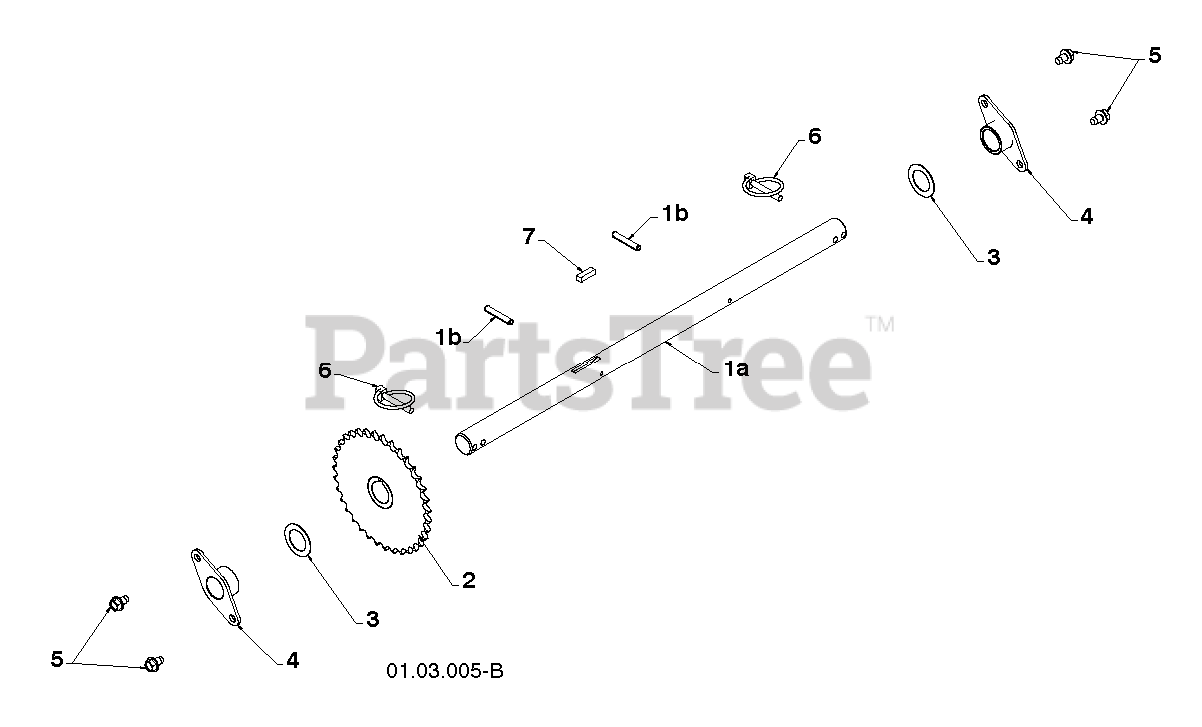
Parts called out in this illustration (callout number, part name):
1	AXLE.SHAFT.ASM.W/ROLPIN.NON-PS
2	SPROCKET.WELDMENT.AXLE.1.00
3	WASHER TRUST 1"
4	BEARING, AXLE
5	Screw 5/16-18 x 1/2 Hex, Self Tapping 5/16-18 x 1/2
6	PIN KLIK, 1/4
7	KEY, SQUARE 1/4 X .875
